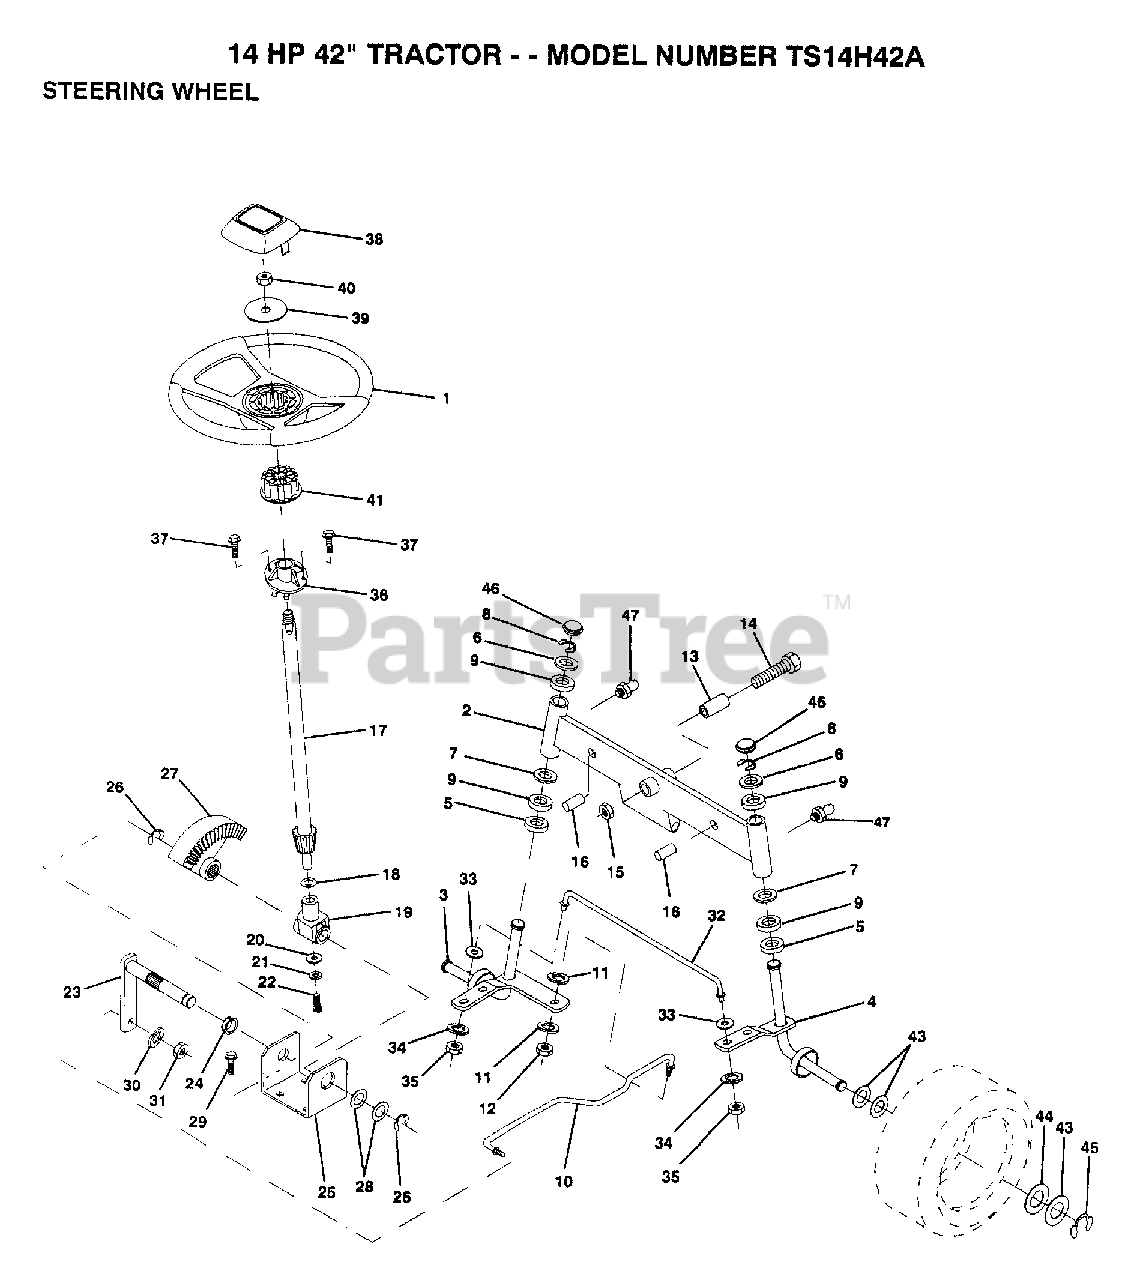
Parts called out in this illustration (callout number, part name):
3	SPINDLE LH
4	SPINDLE RH
5	WASHER .T
6	WASHER
7	WASHER
8	RING
9	COL. SRTG. BEAR.
11	LOCKWASHER
13	BEARING
14	BOLT HEX 5/8-11
15	"NUT-LOC,FLANGE LT"
16	AXLE PIN
17	STEERING SHAFT
18	THRUST WASHER
19	SUPPORT.SHAFT
21	LOCKWASHER
22	"SCREW,SPECIAL"
24	NYLINER T
25	"BRKT,STEERING"
26	RING
27	GEAR SECTOR
28	WASHER .T
29	SCREW
30	LOCKWASHER
32	TIE ROD
33	WASHER M
34	LOCKWASHER
35	NUT.LOCK.5/16-24
38	INSERT CAP STRG WH AUT
39	WASHER
41	ADAPTER LT
43	WASHER
44	WASHER
45	RING
46	CAP
47	ZERK M
